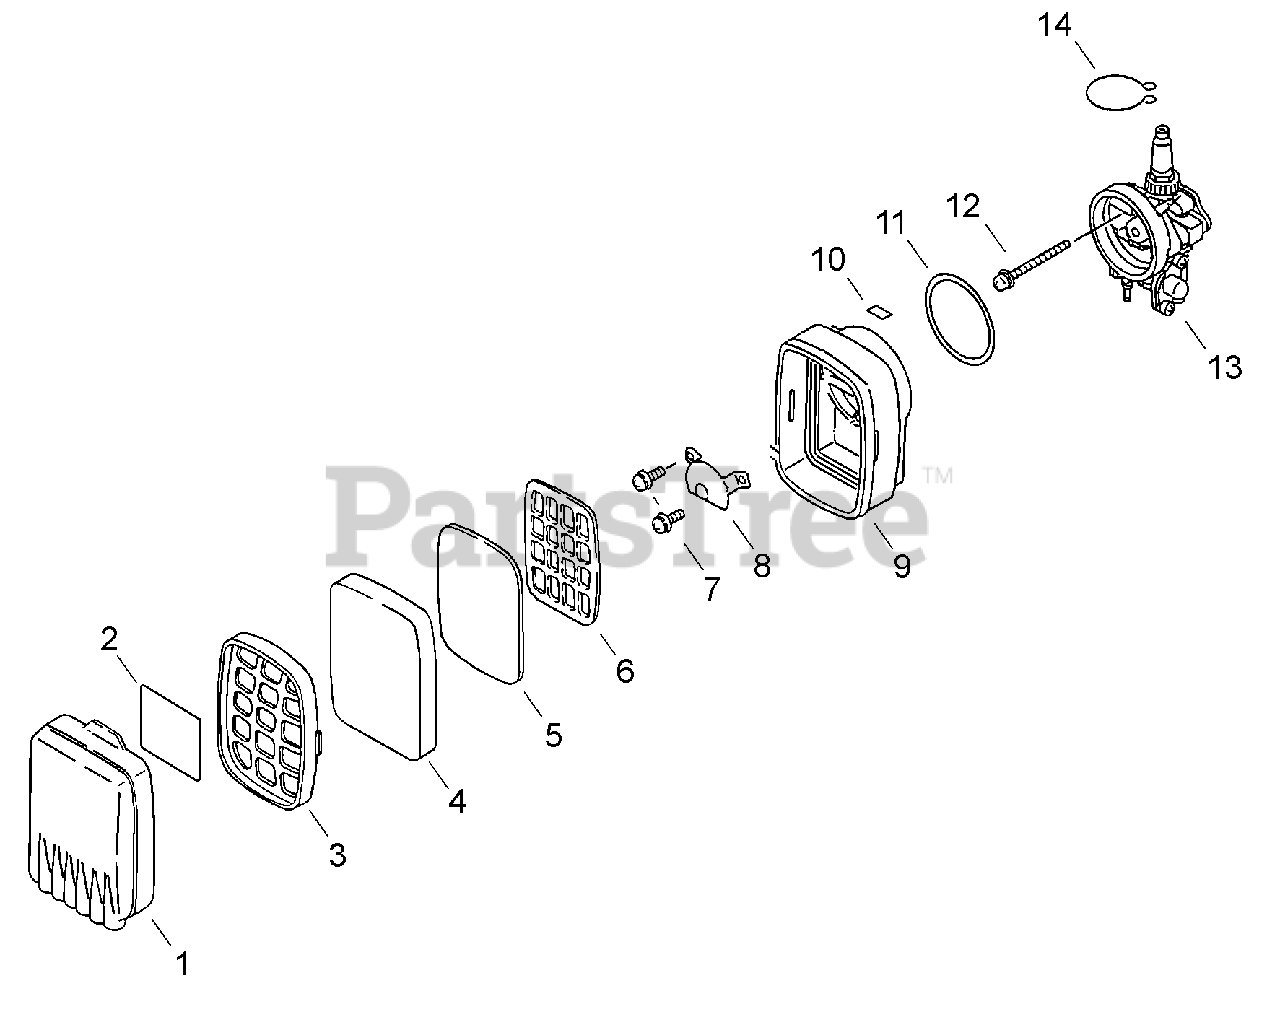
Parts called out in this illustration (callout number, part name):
1	COVER, AIR FILTER
2	LABEL - AIR FILTER
3	RETAINER, AIR FILTER
4	PRE-FILTER -- FOAM
5	FILTER, AIR
6	RETAINER, AIR FILTER
7	SCREW - 4X14
8	PLATE, PREVENT
9	CASE, AIR FILTER
10	LABEL - CHOKE
11	GASKET, INTAKE
12	SCREW - 5X55
13	CARBURETOR
